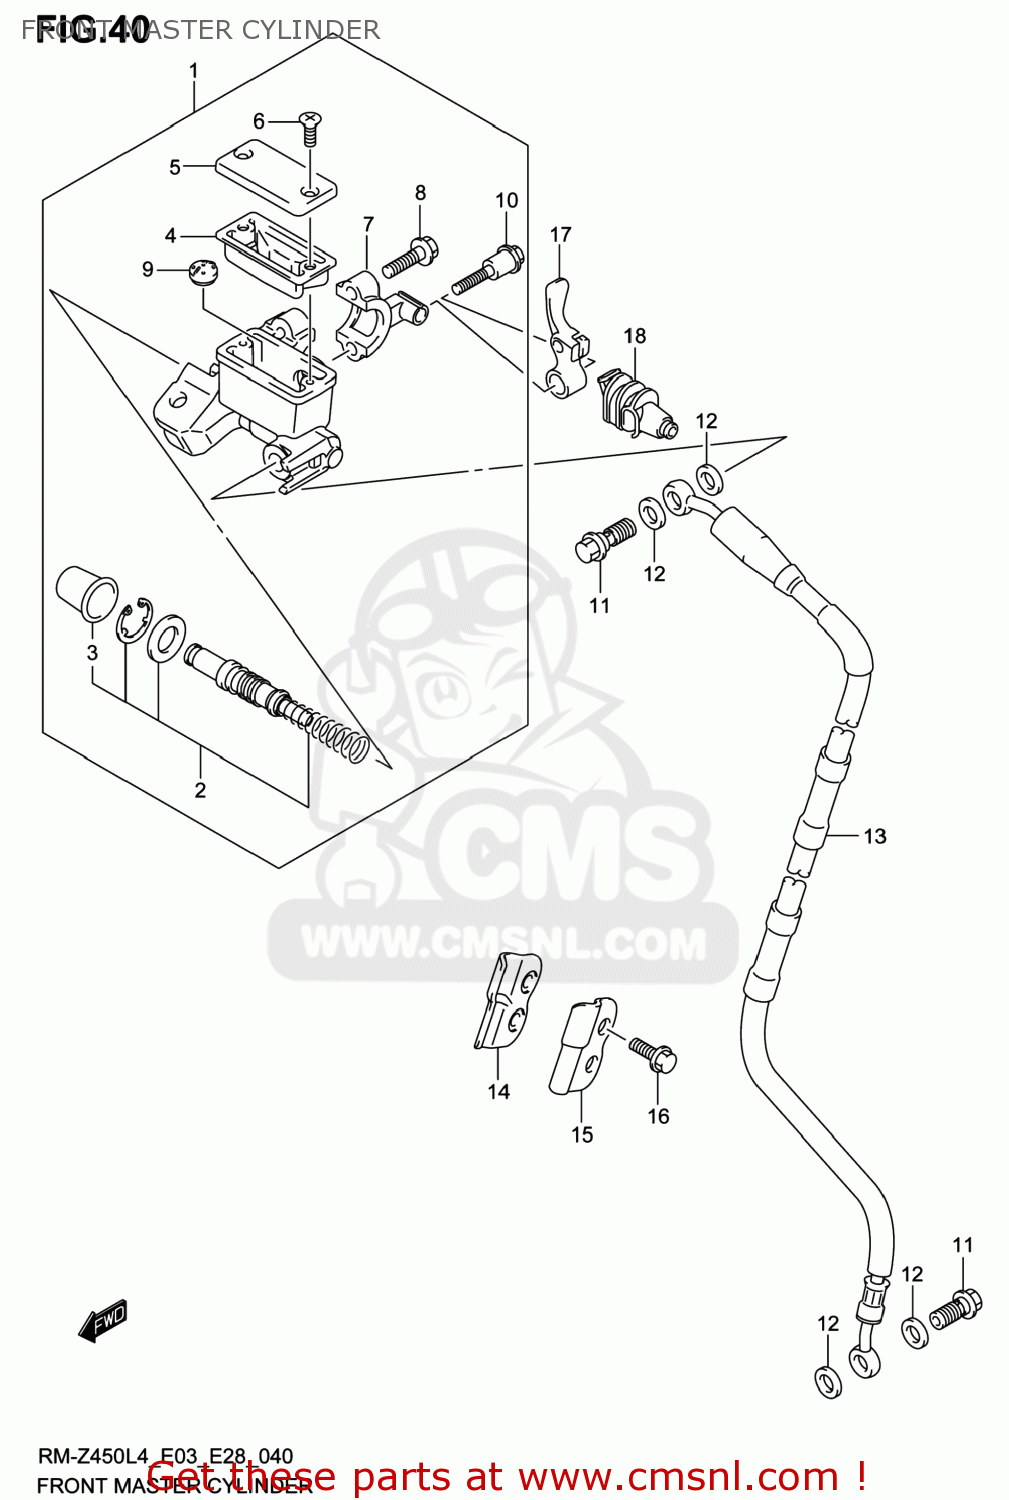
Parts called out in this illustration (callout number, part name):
1	CYLINDER ASSY,FR MASTER
2	PISTON & CUP SET
3	BOOT
4	DIAPHRAGM
5	CAP
6	SCREW
7	HOLDER
8	BOLT
9	SEPARATOR
10	BOLT,MASTER CYLINDER HOLDER
11	BOLT UNION
12	WASHER(10X15X1.5)
13	HOSE,FR BRAKE
14	CLAMP,FR BRAKE HOSE INNER
15	CLAMP,FR BRAKE HOSE
16	BOLT(6X16)
17	LEVER,MASTER CYLINDER HOLDER
18	COVER,MASTER CYL HOLDER LEVER
